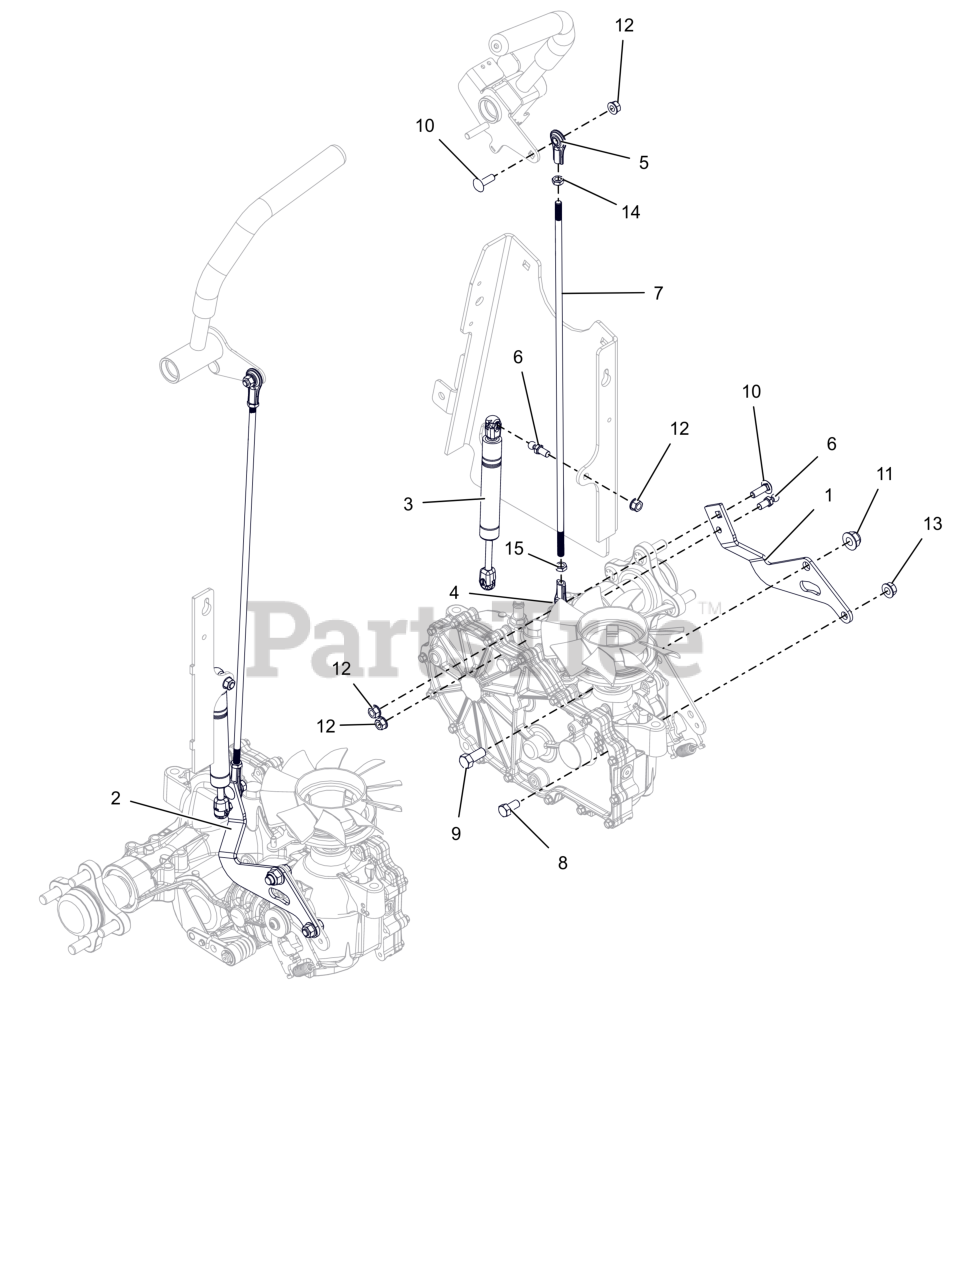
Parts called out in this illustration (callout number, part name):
1	ARM, LH DRIVE CONTROL
2	ARM, RH DRIVE CONTROL
3	DAMPER, CONTROL
4	ALIGNABALL, 5/16 RH THREAD
5	ALIGNABALL, 5/16 LH THREAD
6	STUD- BALL
7	ROD, STEERING
8	BLT,HEX .38-16X.75 G5 ZCC
9	BLT, HEX 0.4375-14X1 GR5 ZCC
10	BLT,RHSSN .31-18X1.00 G5 ZCC
11	NUT,NYL-FLG .44-14 GF ZCC
12	NUT,LK-CTR-FLG .31-18 GF ZCC
13	NUT-LK-CTR-FLG .375-16 GF ZCC
14	NUT, JAM-LH .312-24 ZCC
15	NUT-JAM .312-24 ZCC
